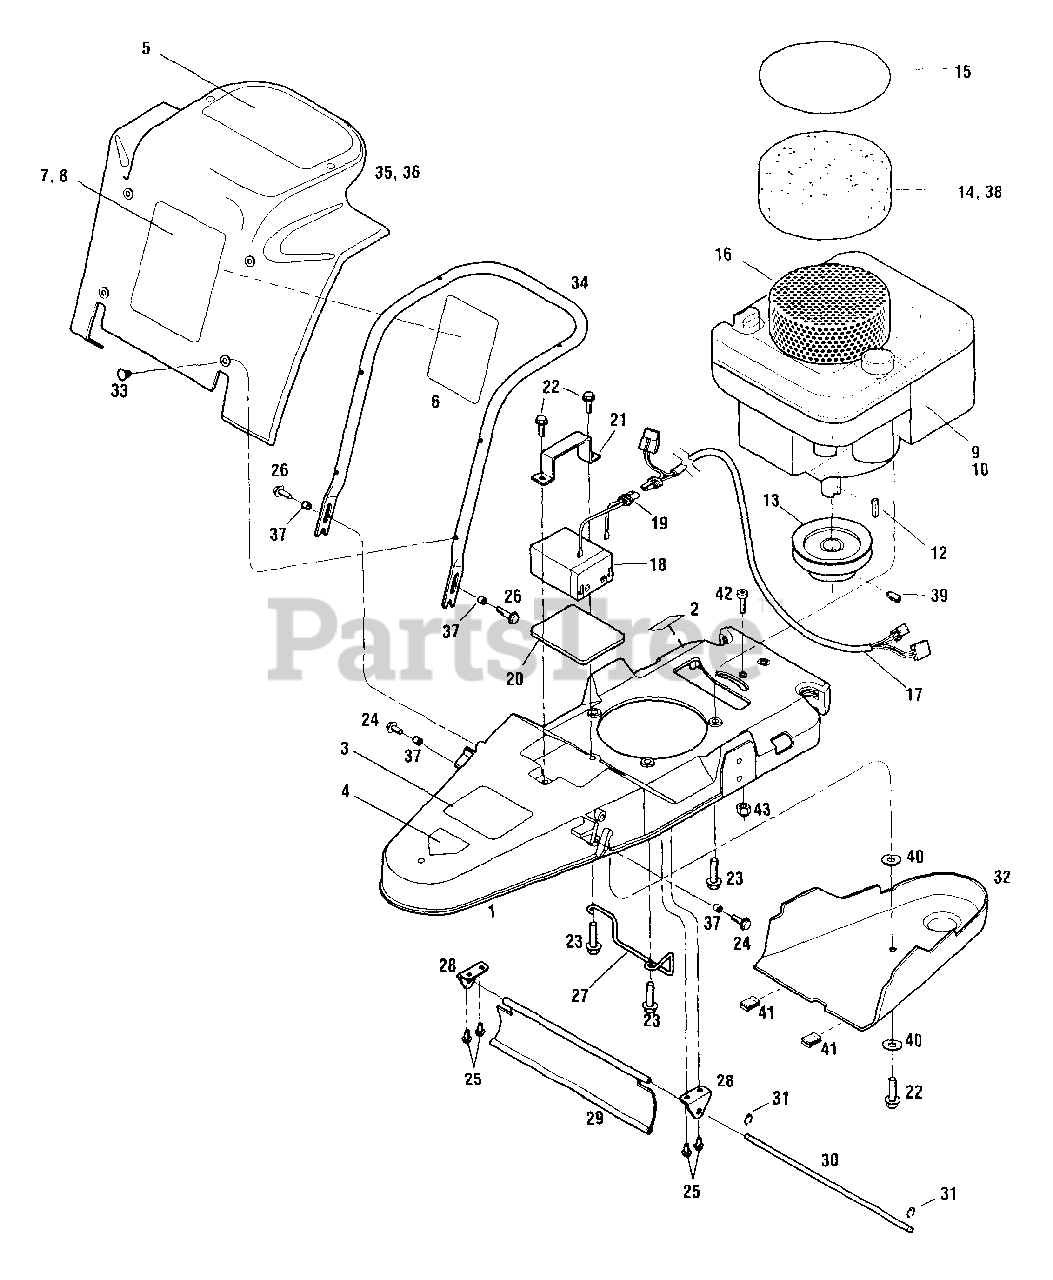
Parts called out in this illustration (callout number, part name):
1	Deck with Decals
2	Decal-Hot Surface
3	Decal-Warning/Thrown Objects
4	Decal-Danger Feet/Hands
5	Decal-Engine Cover
6	Decal-Parallel Trim Control
7	Decal-Logo 6HP
8	Decal-Logo 5HP
10	Engine-6HP Electric
12	Key, 3/16" x 1" SQ
13	Pulley, 4" OD
14	Engine Debris Guard/Foam
15	O-Ring/Engine Debris Guard
16	Engine Debris Guard/Steel
17	Wire Harness
18	Battery
19	Battery Connector
20	Battery Pad
21	Battery Bracket
22	Hex Head Flange Screw, 5/16 x 1
23	Hex Head Flange Screw, 3/8 x 1.50
24	Hex Head Flange Screw, 1/4-20 x 3/4
25	Hex Head Flange Screw, 1/4-20 x 5/8
26	Hex Head Flange Screw, 1/4-20 x 1
27	Belt Guide
28	Flap Bracket
29	Deflector Shield
30	Deflector Shield Rod
31	E-Ring, 5/16"
32	Belt Cover
33	Push-In Fastener
34	Engine Cover Support
35	Engine Cover w/Decals
36	Engine Cover w/Decals
37	Spacer
39	Set Screw
40	Washer
42	Socket Head Capscrew, 1/4-20 x 1
43	Toplock Nut, 1/4-20
